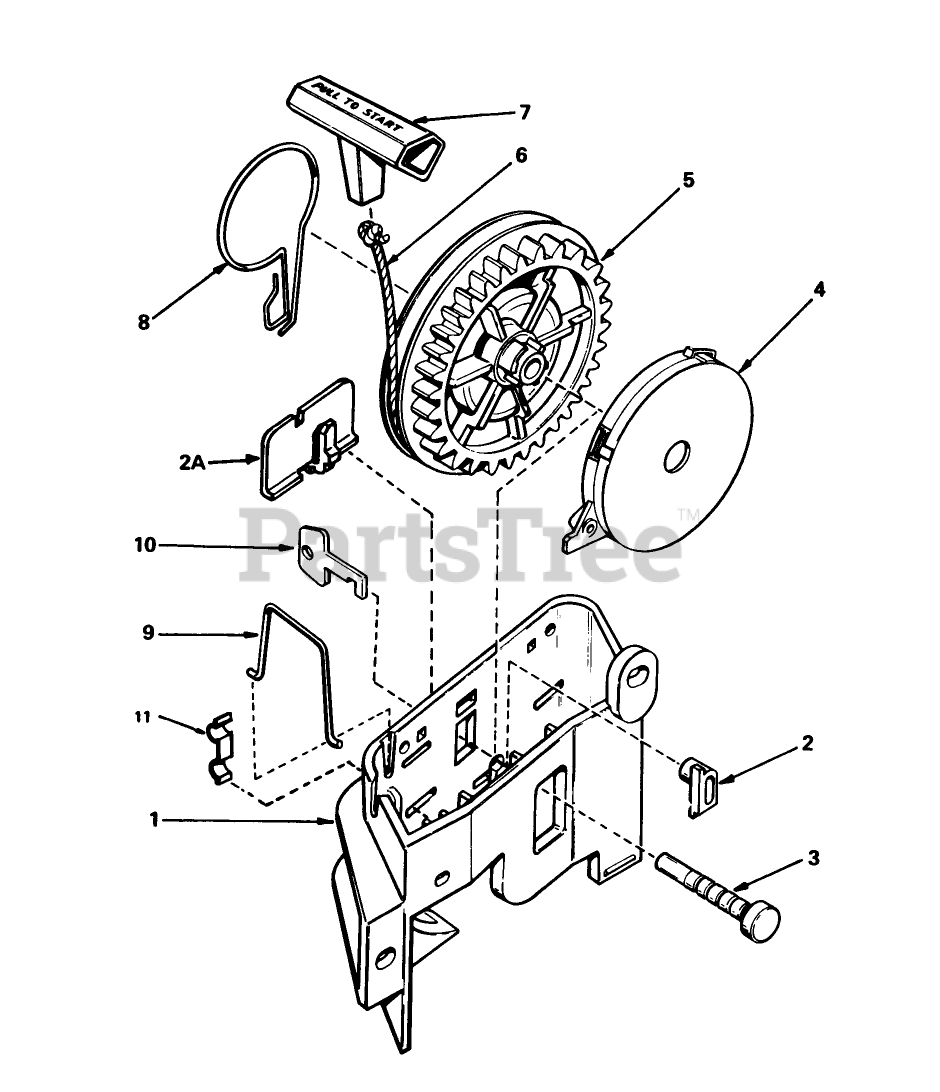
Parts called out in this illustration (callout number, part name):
1	Bracket Starter
2	Pawl, Locking Not used on all engine models)
2A	Clip, Starter Bracket (Used On Starters Not Equipped With Pawl, Ref. No. 2)
3	Pin-Pulley
4	Spring Assy., Rewind (Incl. Ref. #3)
5	Pulley
6	Rope Starter (Length 65" 9/64" Dia.)
7	Handle-Starter
8	Brake
9	Clip-Rope
10	Key (Not Used On All Engine Models
11	Washer-Thrust
